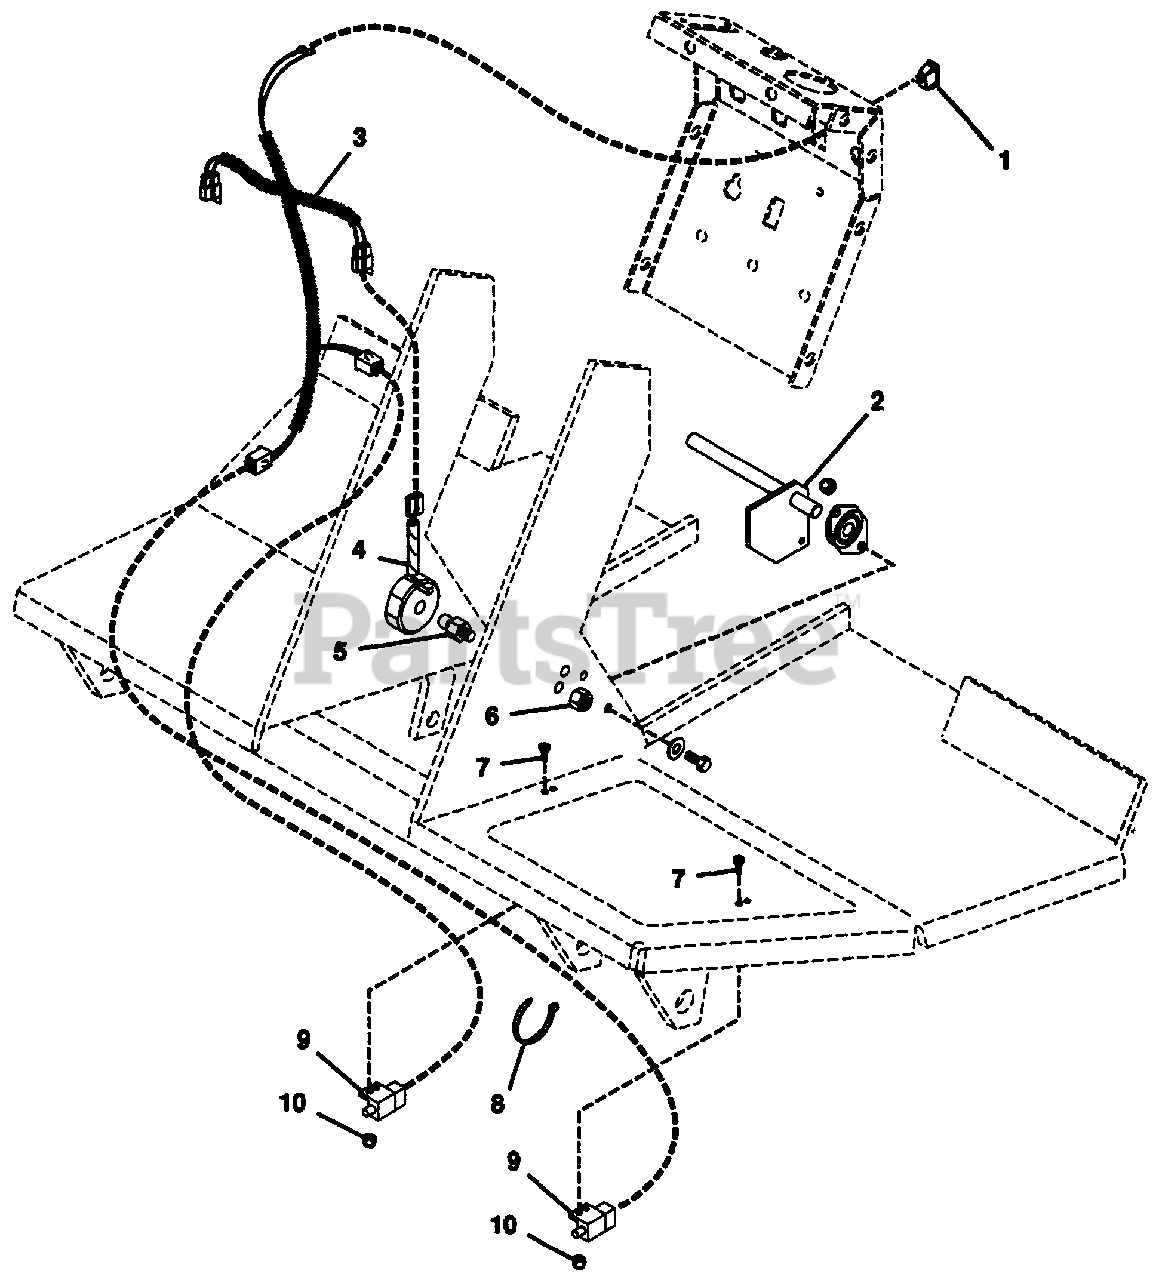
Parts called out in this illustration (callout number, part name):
1	Switch, Light
2	Weldment, Control
3	Harness, Wiring
4	Assembly, Magnet
5	Pin, Magnet
6	Nut, Lock 1/2-13
7	Screw, Machine 10-24x.625 PHD
8	Tie Wrap, Black
9	Switch, Interlock
10	Nut, Lock 10-24
